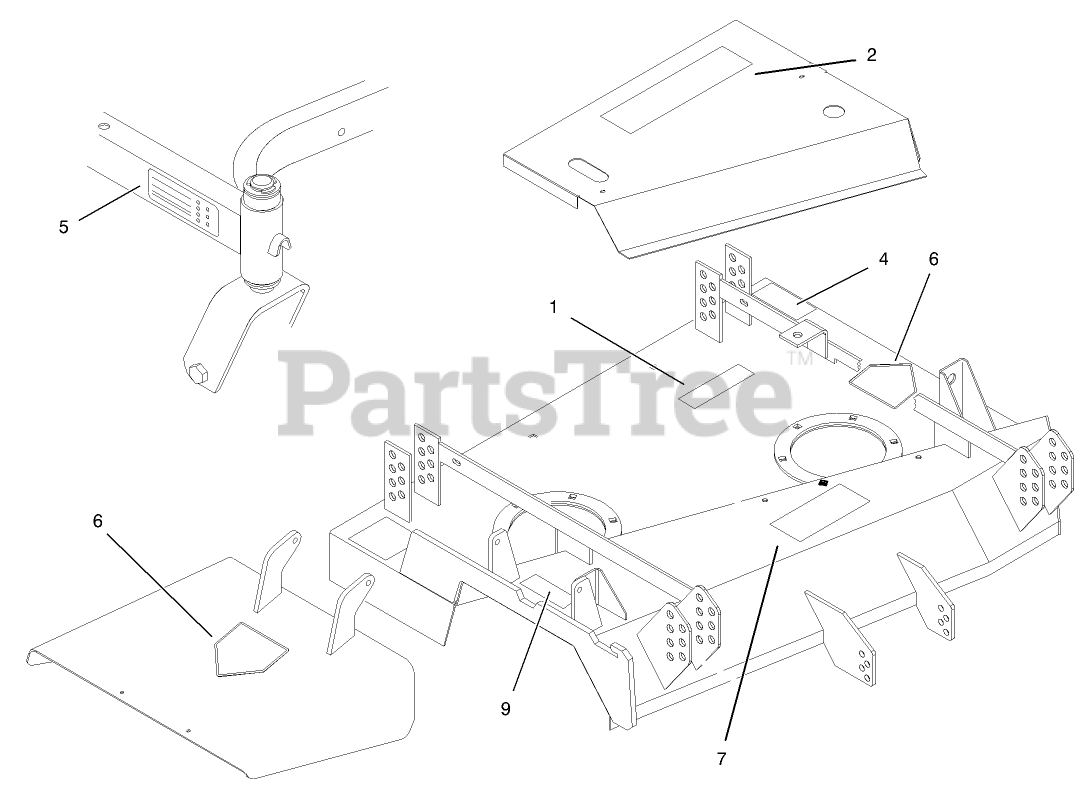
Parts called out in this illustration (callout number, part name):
1	DECAL-DANGER
2	Decal-Proline, 92cm
4	DECAL-TORQUE, BLADE BOLT
5	DECAL-HOC
6	DECAL-DANGER
7	DECAL-DANGER
9	DECAL-WARNING, DEFLECTOR
